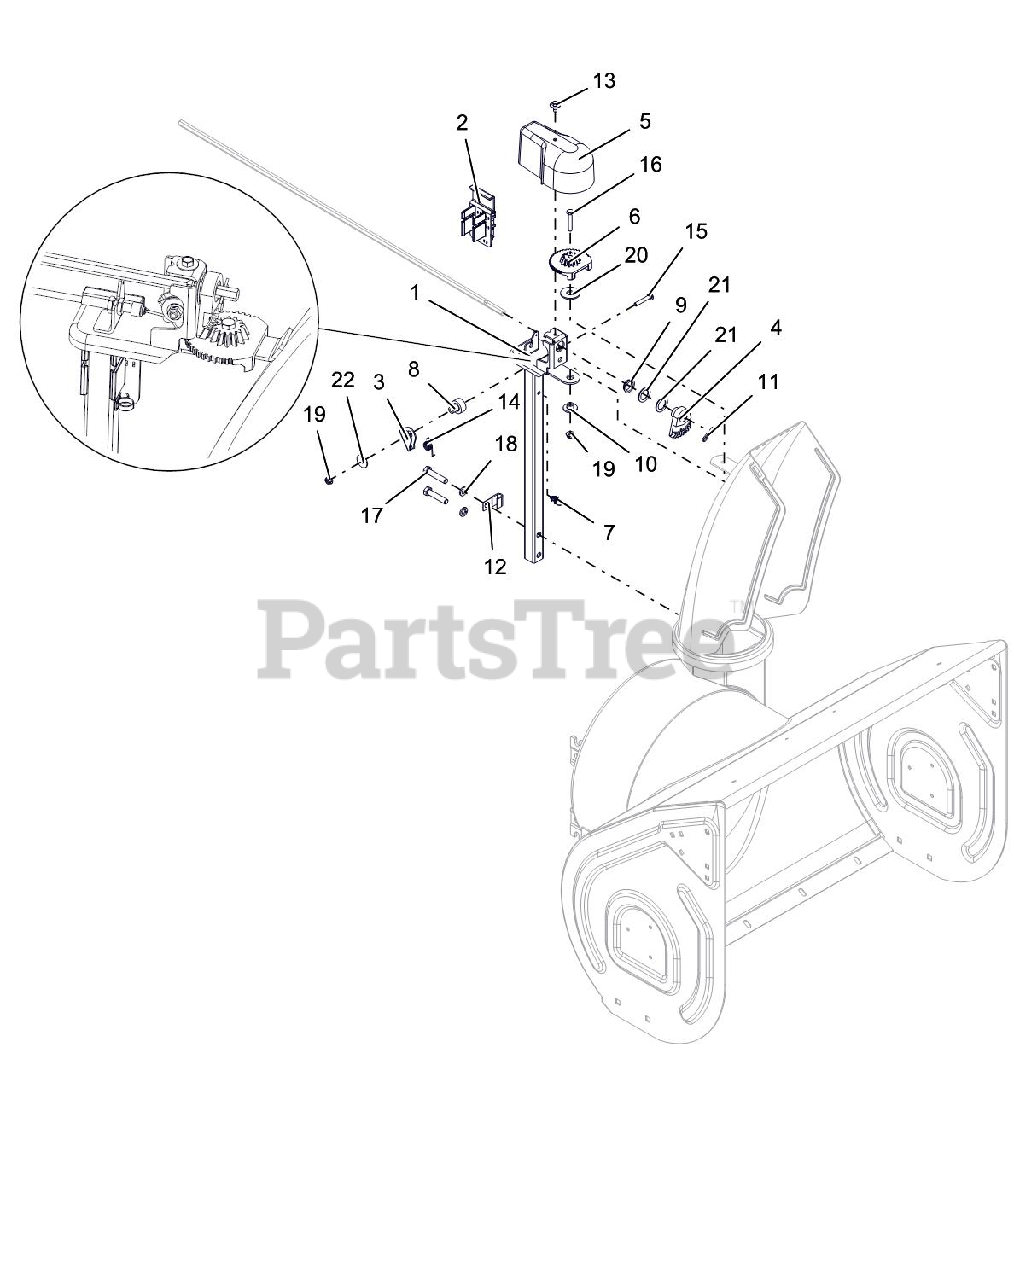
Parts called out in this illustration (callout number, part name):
1	PEDESTAL, CHUTE - QUICK STICK
2	HOLDER W LARGE SHEAR BOLT /NUT
3	ARM, LOCKING
4	GEAR, CHUTE-ACTUATION
5	COVER, CHUTE GEAR
6	GEAR, CHUTE
7	CLIP, CABLE GUIDE
8	BUSHING, LOCK ARM
9	BUSHING, POLYLINER-.75 SNAPIN
10	BSHG-FLG .265X.477X.375X1.00
11	PIN-HAIR INT .08X.18X1.18 YWZC
12	J-CLAMP
13	SCR-TAP .25-20X.50 LGHWH TR YZ
14	SG-TORS
15	@BLT-RDHDSQNK .25-20X1.50 G5YZ
16	@BLT-HEX .25-20X1.50 GR5 YWZC
17	@BLT-HEX .38-16X1.75 GR5 YWZC
18	@WSHR-LK .38X.094 REG YWZC
19	@NUT-LK-CTR-FLG .25-20 YWZC
20	WSHR-FLT-NYL .515X1.375X.093
21	WSHR-FL-STL.754X1.125X.062YWZC
22	WSHR-FL-STL .281X1.000X.063
